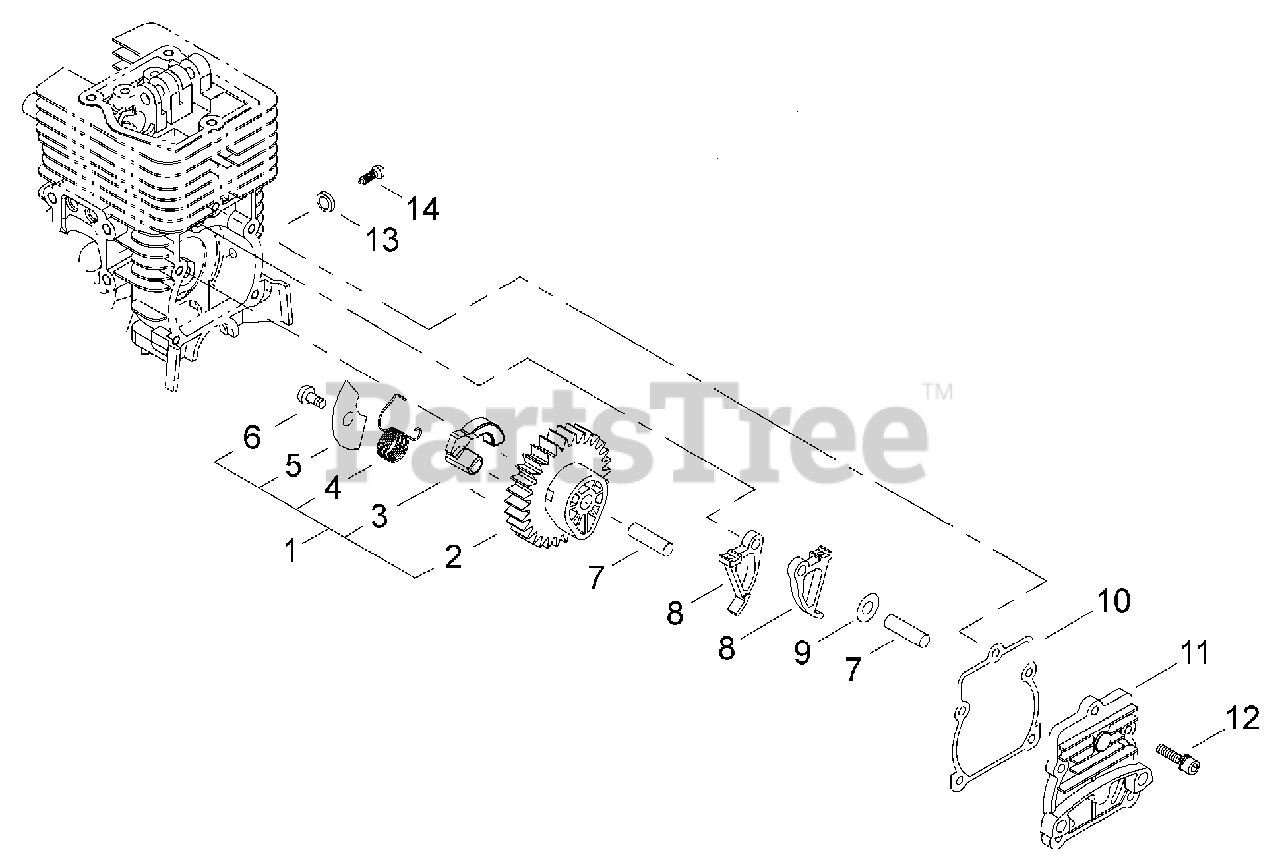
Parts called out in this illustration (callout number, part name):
1	CAM GEAR ASSY
2	GEAR, CAM
3	WEIGHT
4	SPRING
5	PLATE, COVER
6	SCREW, TAPPING 4×6
7	PIN, LOCATING Ø5×29.8 MM
8	FOLLOWER, CAM
9	WASHER 5 MM
10	GASKET, CAM GEAR
11	COVER, CAM GEAR
12	BOLT M4×14
13	WASHER Ø10ר5.5×2
14	SCREW M5
